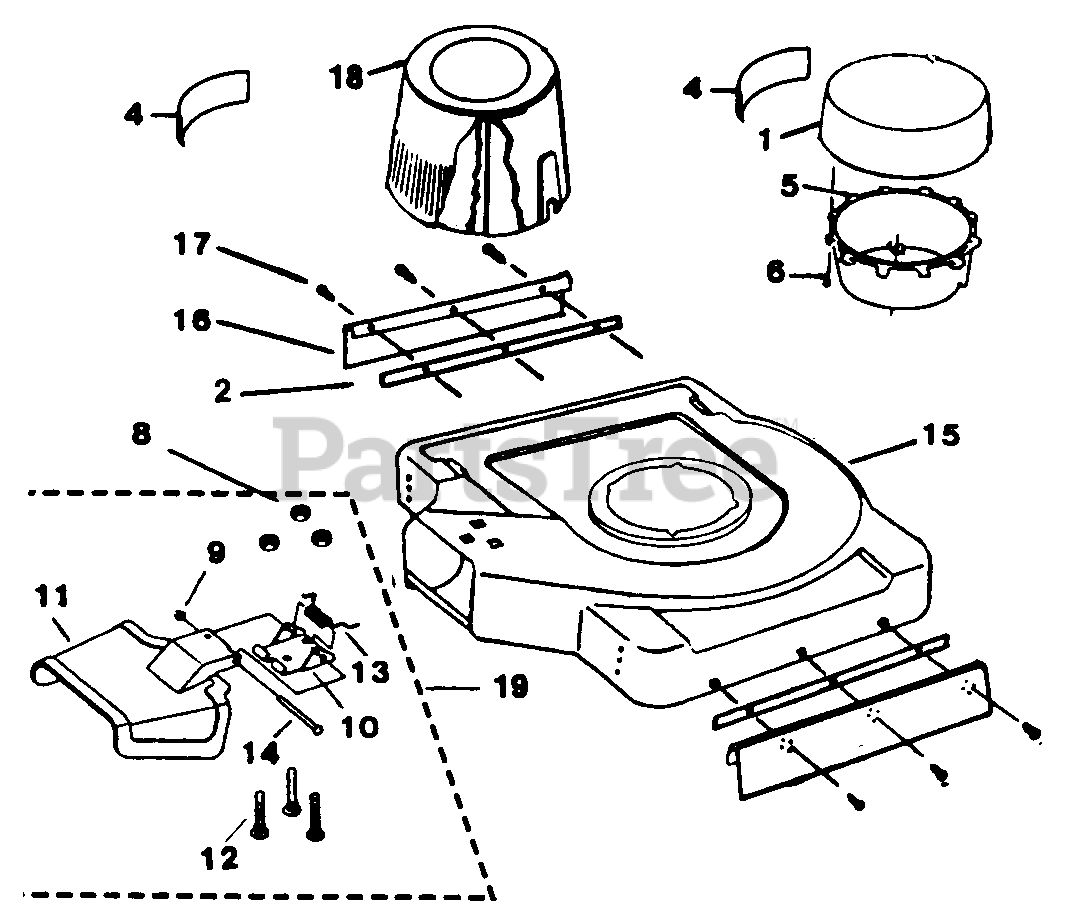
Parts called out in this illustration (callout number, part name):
1	Motor Cover- Top
2	Strap
4	Label - Caution & Data
5	Motor Cover - Bonom
6	Screw
8	1/4" - 20 Locknut
9	Bunon Retainer
10	Hinge Bracket
11	Guard - Chute (Plastic)
12	1/4" - 20 x 5/8" Carriage Bolt
13	Spring
14	Hinge Pin
15	19" Deck
16	Drag Guard
17	Blind Rivet
18	Motor Cover
19	ChuteGuardAss'y. (Plastic)
